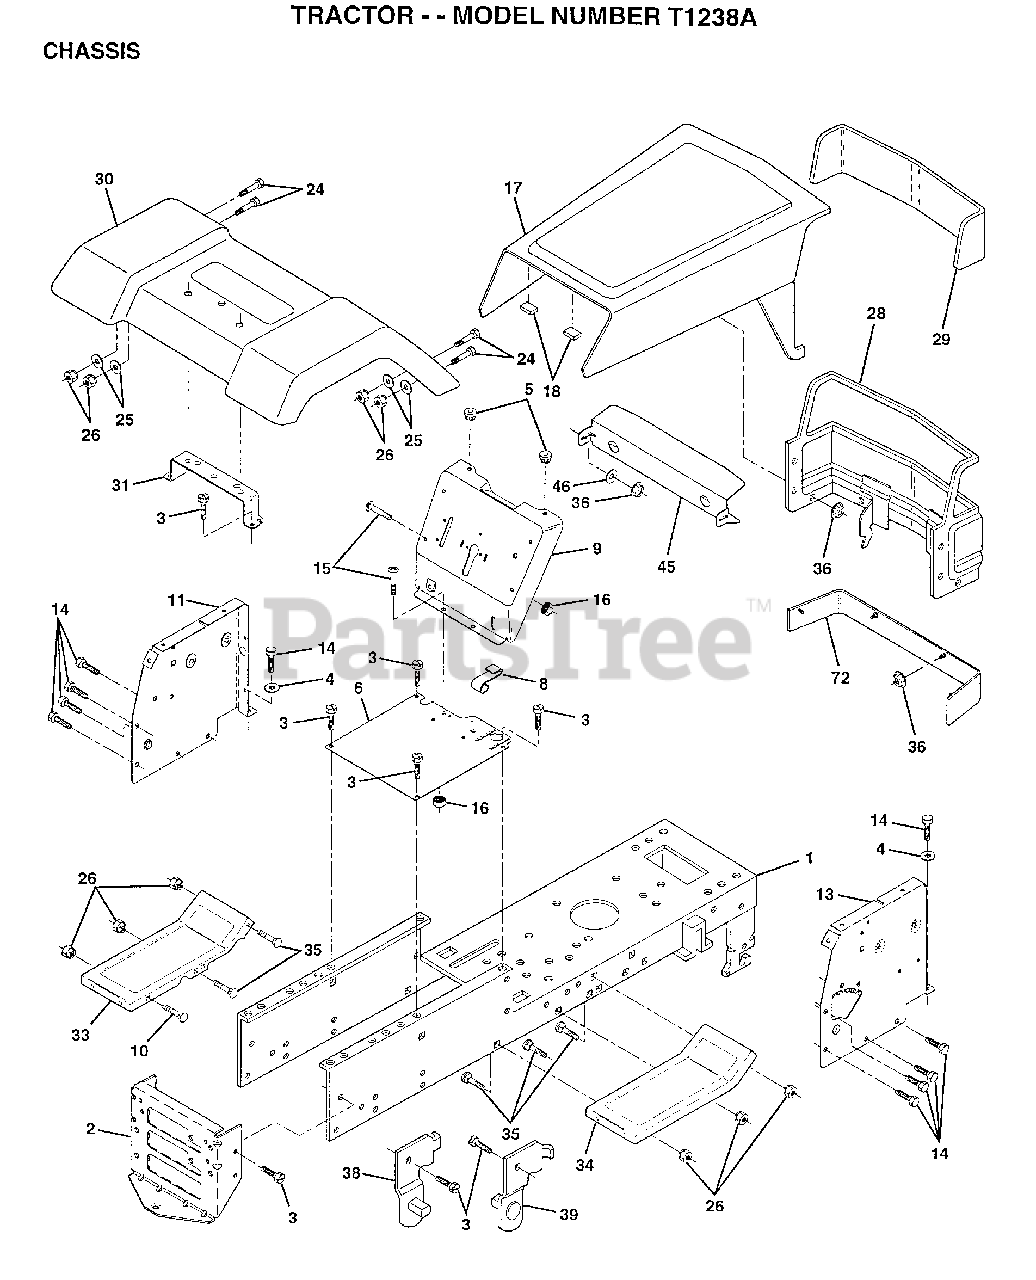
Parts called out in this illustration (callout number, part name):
1	CHASSIS.WLD.11GA
3	SCREW
4	WASHER
8	"CLIP,INSULATOR"
9	DASH.SLKSC.LT.1PC
11	PANEL.DASH.LH.
14	SCREW LT
15	SCREW
17	HOOD.W/SD.PNLS.LT
24	BOLT
25	WASHER
26	NUT
28	GRILLE.RALLY.BAR.
29	LENS SERVICE KIT
31	BRKT FENDER
33	FOOTREST.LH.PERF.
34	FOOTREST.RH.PERF.
35	BOLT
36	PAL NUT LT
38	BRACKET ASM LH
39	BRACKET ASM RH
46	RETAINER
72	STRAP.GRILLE.PNT.
